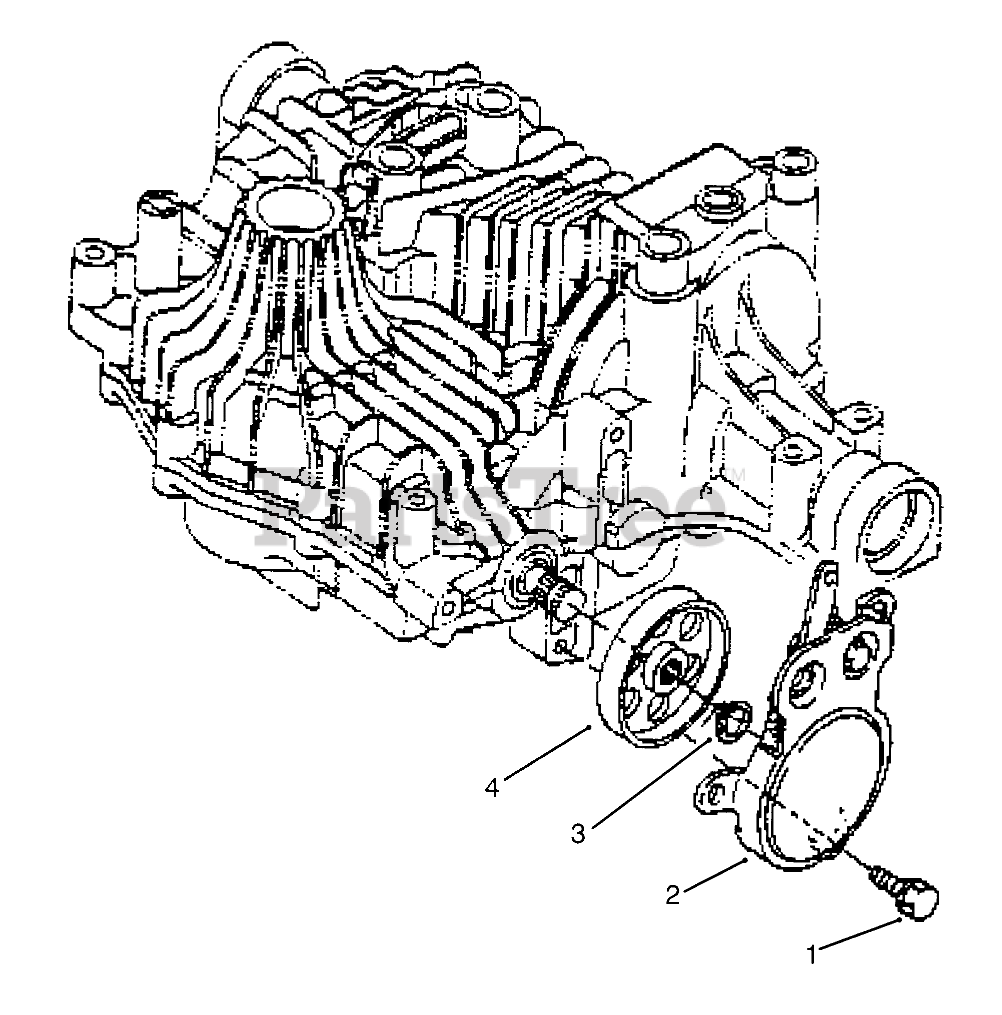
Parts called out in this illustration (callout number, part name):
1	BOLT AND WASHER ASM
2	BAND-BRAKE INTERLOCK
3	RING-SNAP
4	DRUM-BRAKE
